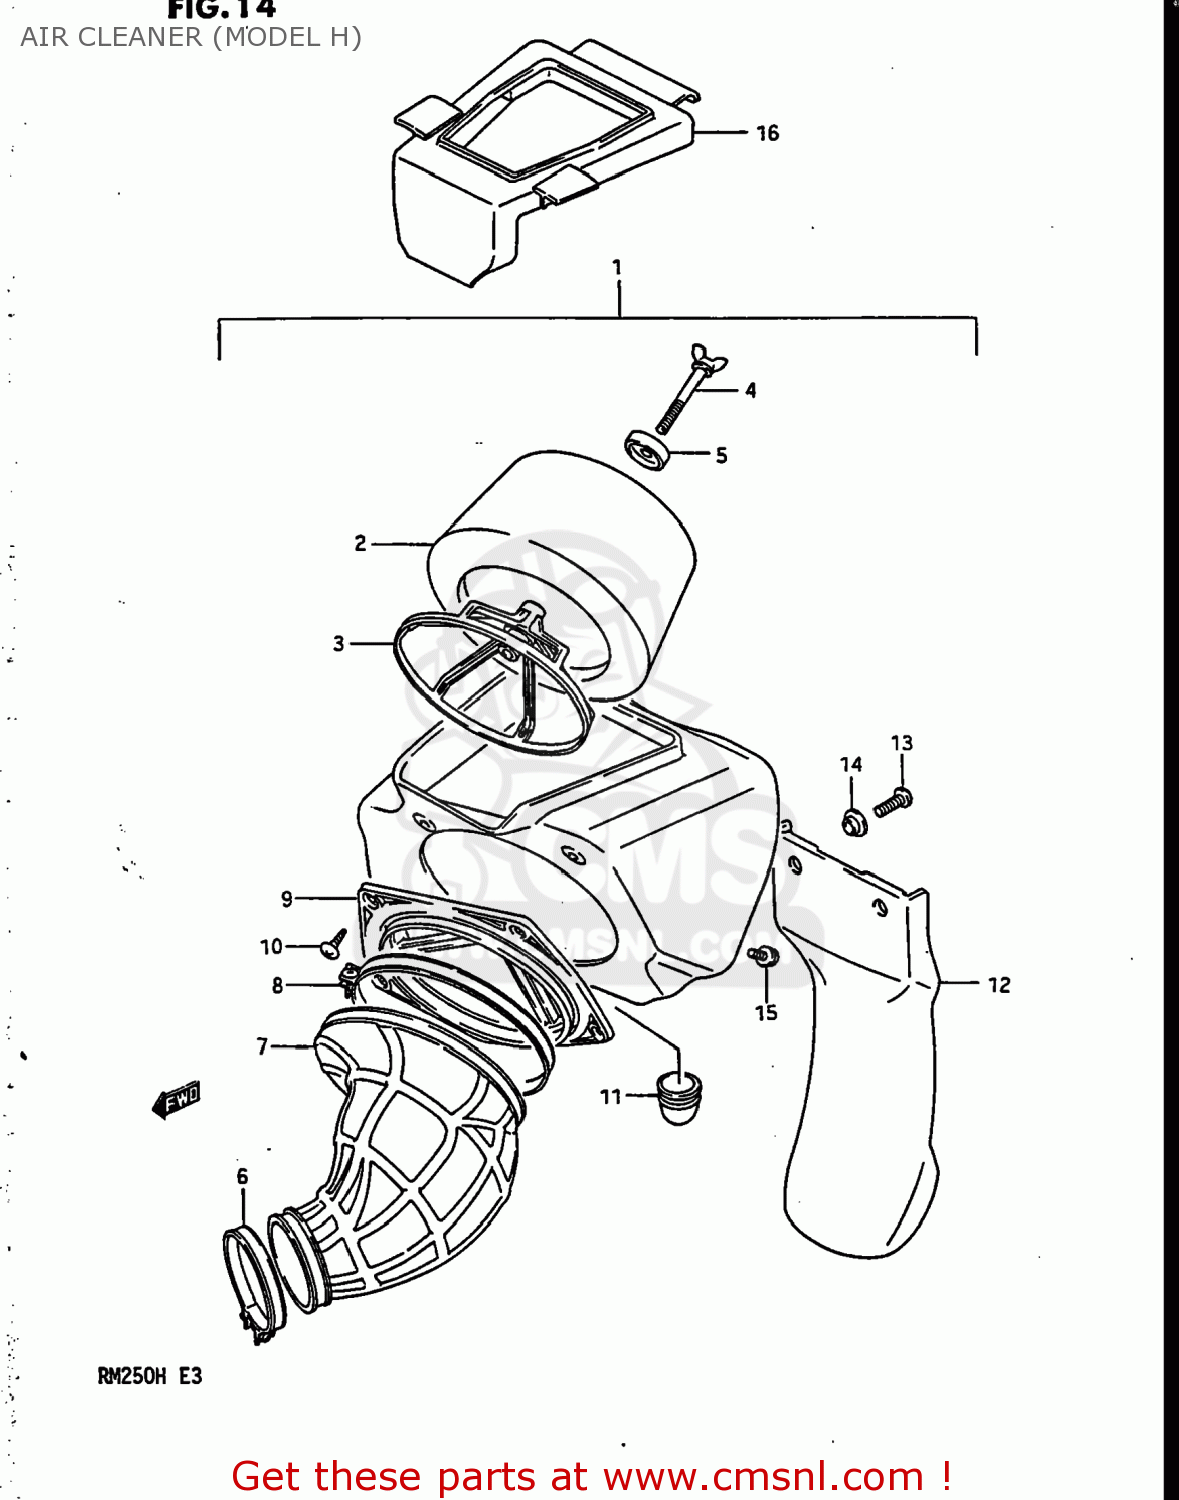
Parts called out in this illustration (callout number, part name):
1	CLEANER ASSEMBLY,AIR
2	FILTER,AIR CLEANER
3	HOLDER,FILTER
4	BOLT,WING
5	WASHER,AIR CLEANER
6	CLAMP
7	TUBE,AIR CLEANER OUTLET
8	CLAMP
9	HOLDER,FILTER
10	SCREW
11	HOSE,AIR CLEANER DRAIN
12	GUARD,MUD
13	SCREW
14	COLLAR
15	BOLT 6X12
16	GUARD,MUD
